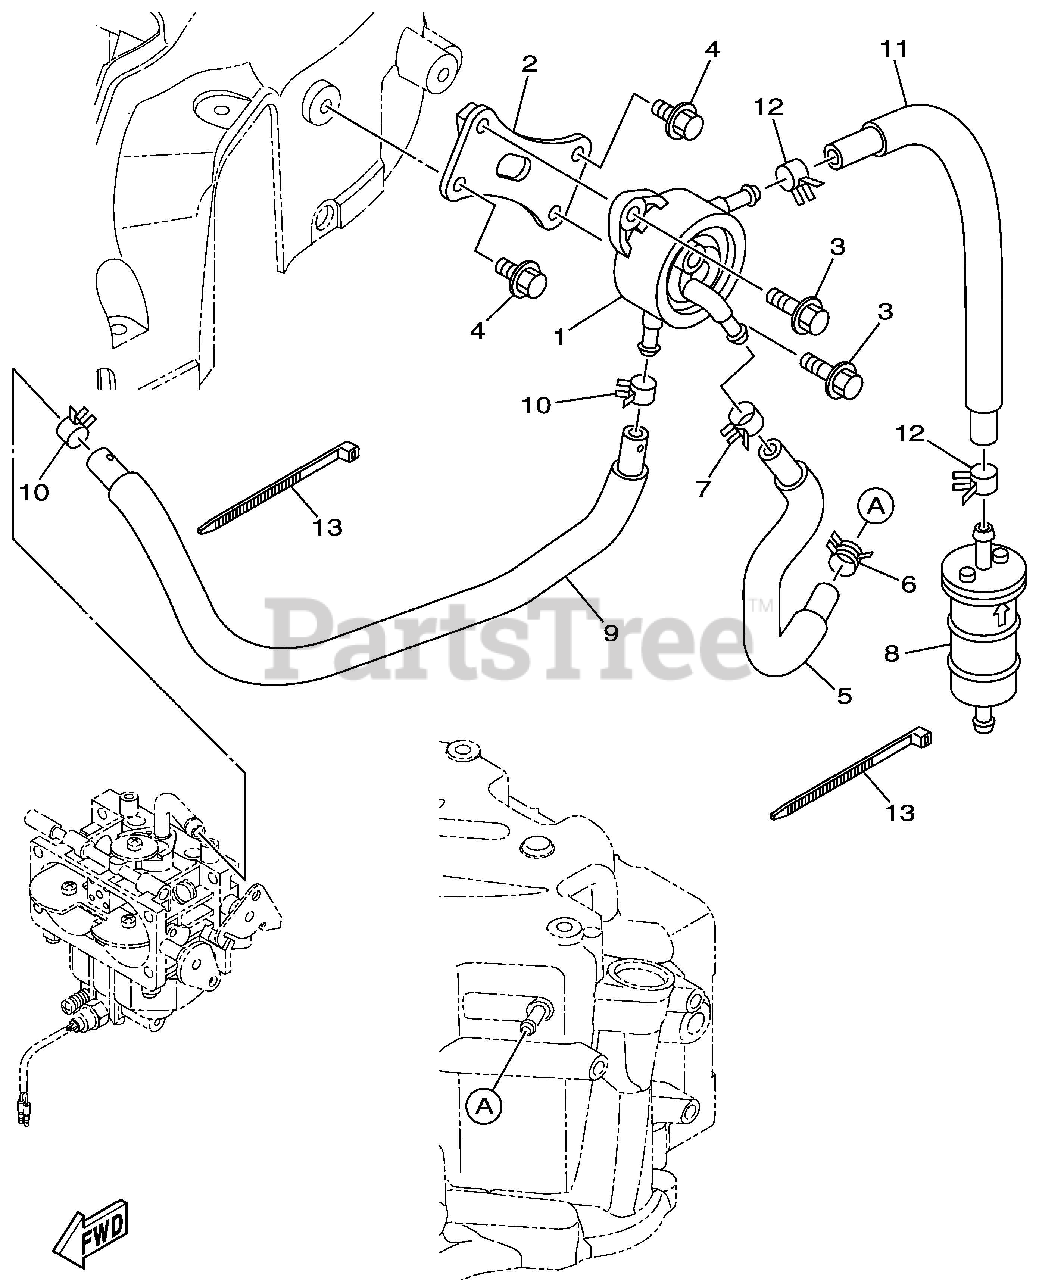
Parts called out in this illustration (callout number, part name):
1	FUEL PUMP ASSY
2	BRACKET, FUEL PUMP 2
3	BOLT, FLANGE
4	BOLT, FLANGE
8	FILTER-FUEL YAMAHA 824
9	PIPE, FUEL 1
11	PIPE, FUEL 2
